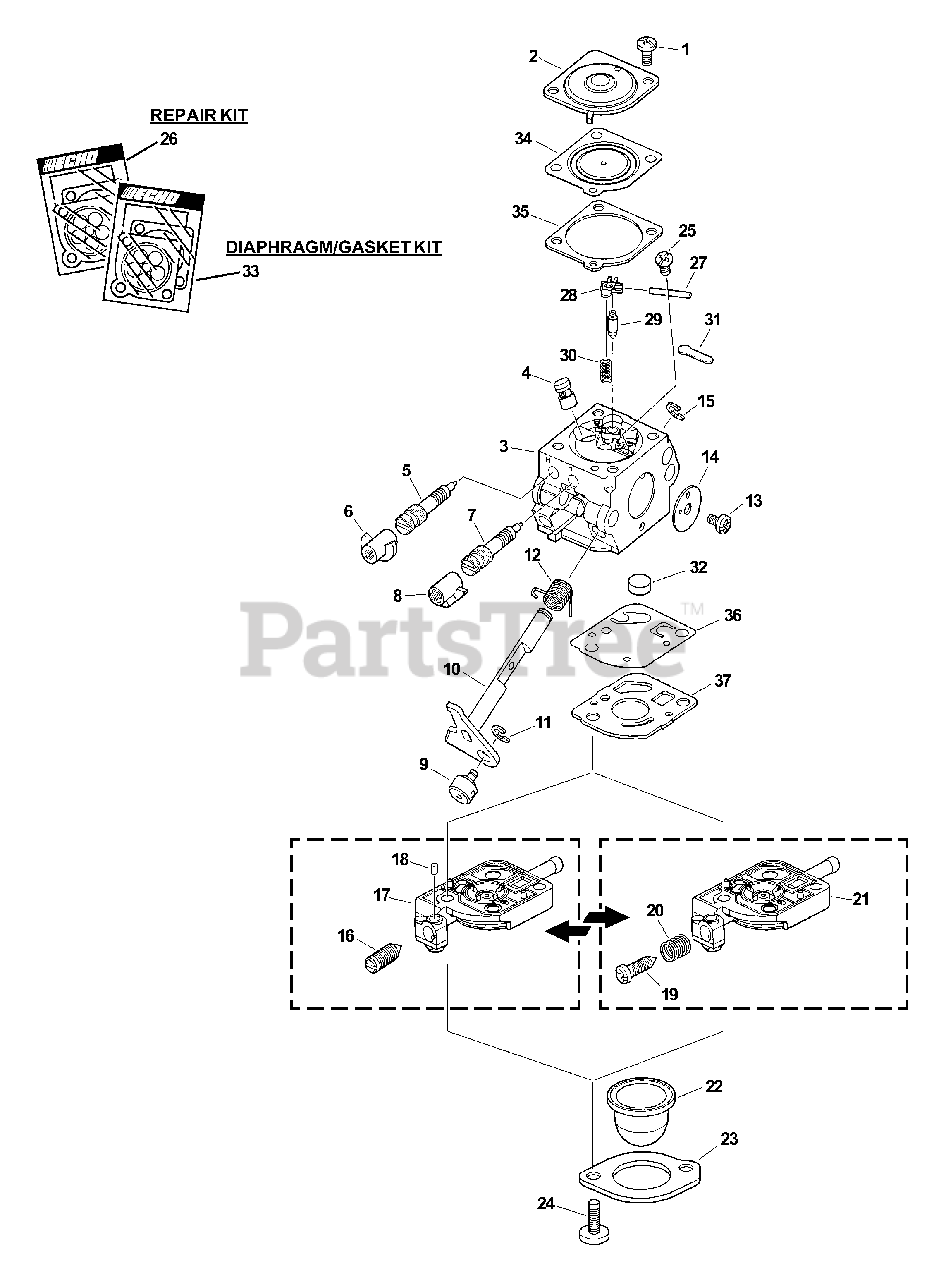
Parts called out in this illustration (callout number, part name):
2	COVER, METERING DIAPHRAGM
3	BODY, CARBURETOR
4	NOZZLE, CHECK VALVE
5	NEEDLE, HIGH SPEED
6	CAP, LIMITER - RED
7	NEEDLE, LOW SPEED
8	CAP, LIMITER - WHITE
10	SHAFT, THROTTLE
12	SPRING, THROTTLE RETURN
14	VALVE, THROTTLE
16	SCREW, IDLE ADJUST
17	BODY ASSY, PURGE
18	PIECE, FRICTION
19	SCREW, THROTTLE ADJUST
21	BODY ASSY, PURGE
22	BULB, PURGE
23	RETAINER
26	REPAIR KIT, CARBURETOR
27	PIN, METERING LEVER
28	LEVER, METERING
29	VALVE, INLET NEEDLE
30	SPRING, METERING LEVER
31	PLUG, WELCH
32	STRAINER
33	GASKET / DIAPHRAGM KIT
34	DIAPHRAGM, METERING
35	GASKET, METERING
36	DIAPHRAGM, PUMP
37	GASKET, PUMP
